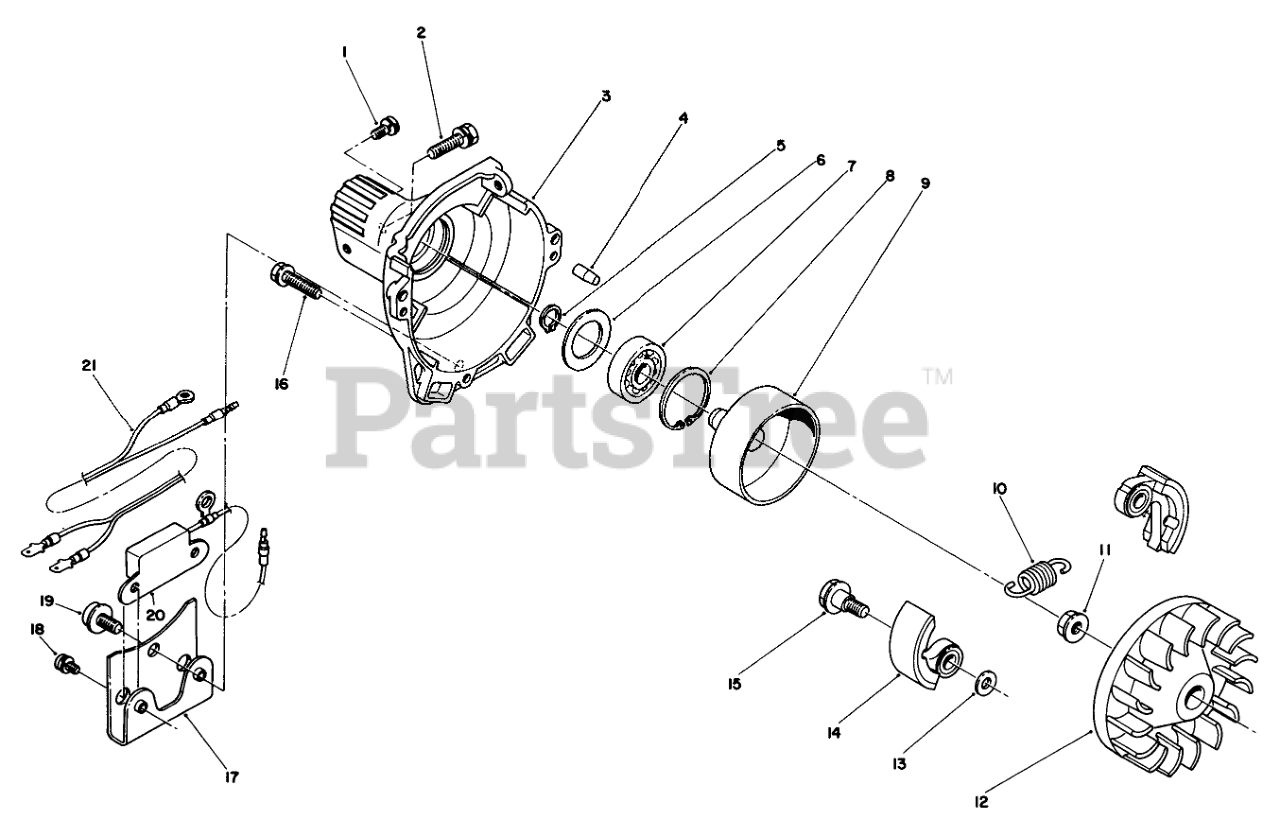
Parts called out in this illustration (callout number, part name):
1	Screw
3	CLUTCH CASE
5	SNAPRING
6	Washer
7	BEARING
8	SNAPRING
9	CLUTCH DRUM
10	Spring
12	Fan
13	Washer
14	SHOE, CLUTCH
15	Bolt-Clutch
16	BOLT & WASHER
17	Bracket-Unit
18	SCREW W/ WASHER
19	SCREW & WASHER
20	Unit-Transistor
21	Wire-Lead
